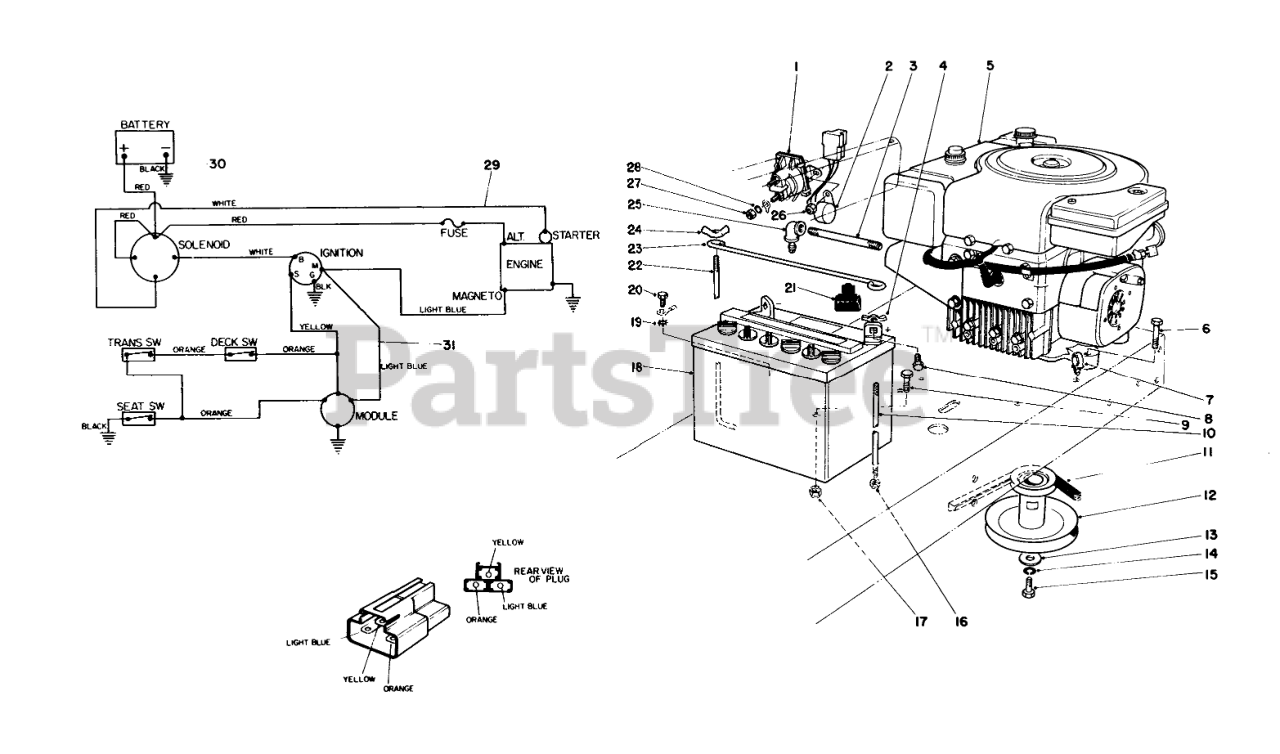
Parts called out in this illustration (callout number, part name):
1	SOLENOID
2	Module Interlock
3	NIPPLE
4	NUT-WING
6	SCREW-HH
7	Clip-Cable
8	SCREW-HH
9	SCREW-HH
10	BATTERY BOLT
11	V-BELT, TRACTION
12	PULLEY
13	WASHER
14	WASHER-LOCK
15	SCREW-HH
16	NUT-KEPS
17	NUT-LOCK, CONE
18	Battery
19	WASHER-LOCK, INTERNAL
20	SCREW-HHF
21	BOOT-TERMINAL
22	ROD-SUPPORT, BATTERY
23	BATTERY HOLD DOWN
24	NUT-WING
25	ELBOW-90 DEGEE
26	NUT-LOCK, CONE
27	Nut-Hex Jam
28	WASHER-LOCK
29	Wiring Harness
30	Wire-Battery to Ground
31	Wiring Harness
